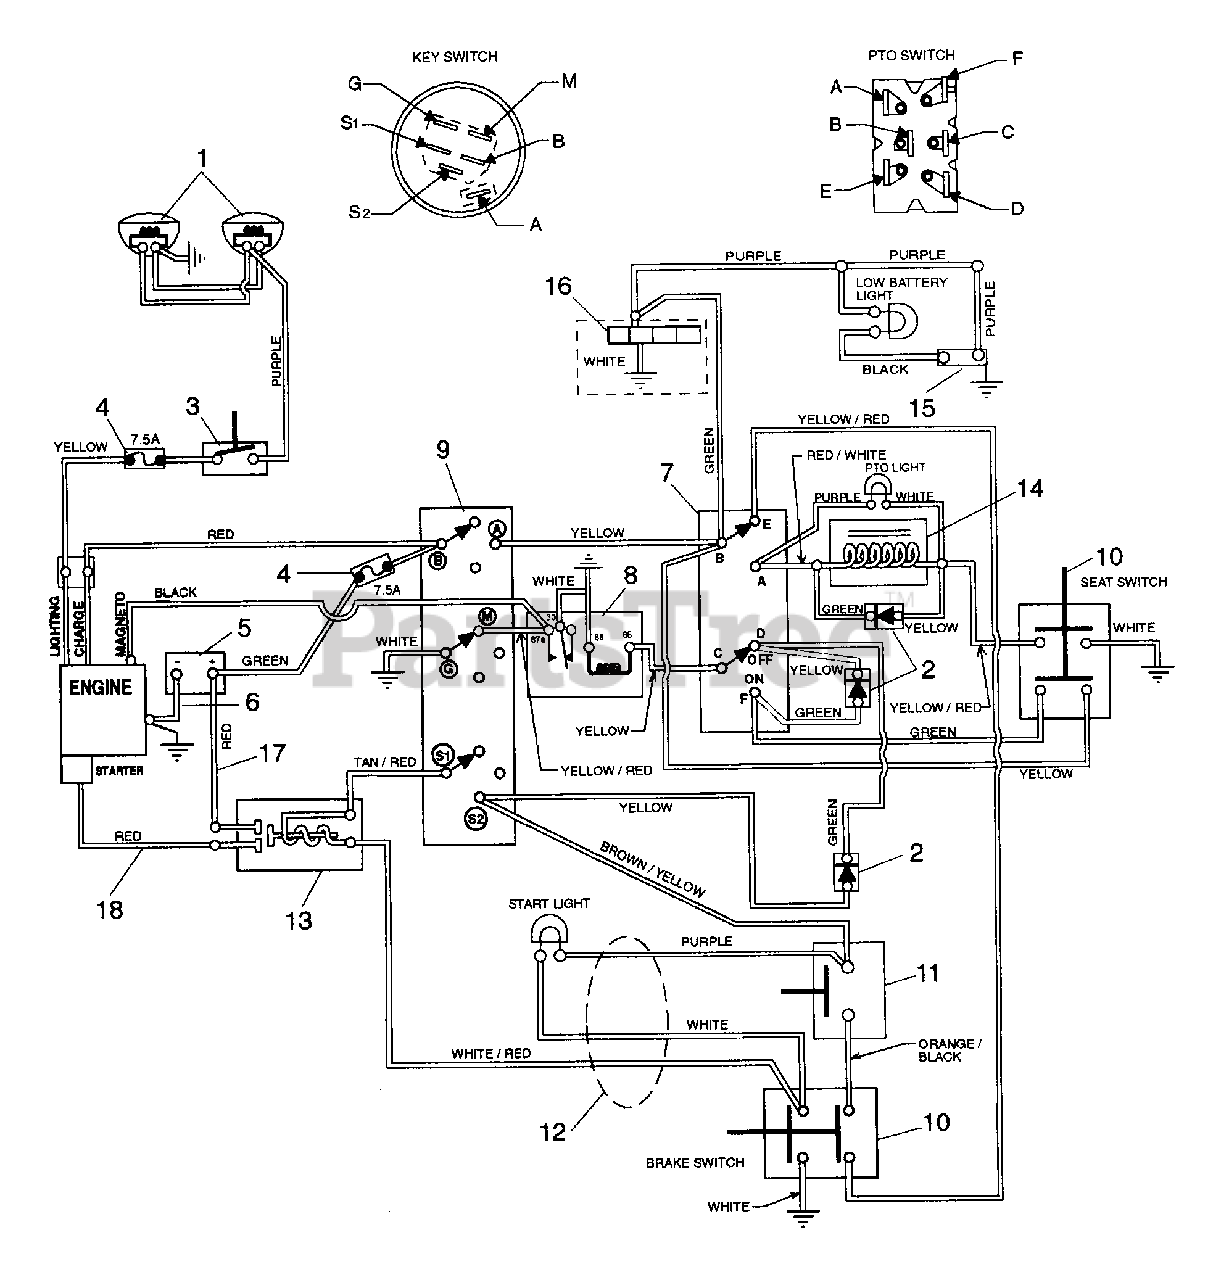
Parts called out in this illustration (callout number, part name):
1	HEADLIGHT- L.H.
1	HEADLIGHT- R.H.
2	DIODE & HOUSING
3	LIGHT SWITCH
4	7.5 Amp Fuse
5	BATTERY W/TUBE
6	GROUND CABLE .31X22.00X.31
7	SWITCH ASSEMBLY- PTO
8	RELAY
9	KEY SWITCH
10	SWITCH- DOUBLE POLE N.O./N.O.
11	SWITCH, NEUTRAL START N.C.
12	WIRE HARNESS- YT130G
13	SOLENOID
14	ELECTRIC CLUTCH/BRAKE(1.8AMP)
15	VOLTAGE SENSOR
16	HOURMETER
17	START CABLE 22"
18	STARTER CABLE 13"
